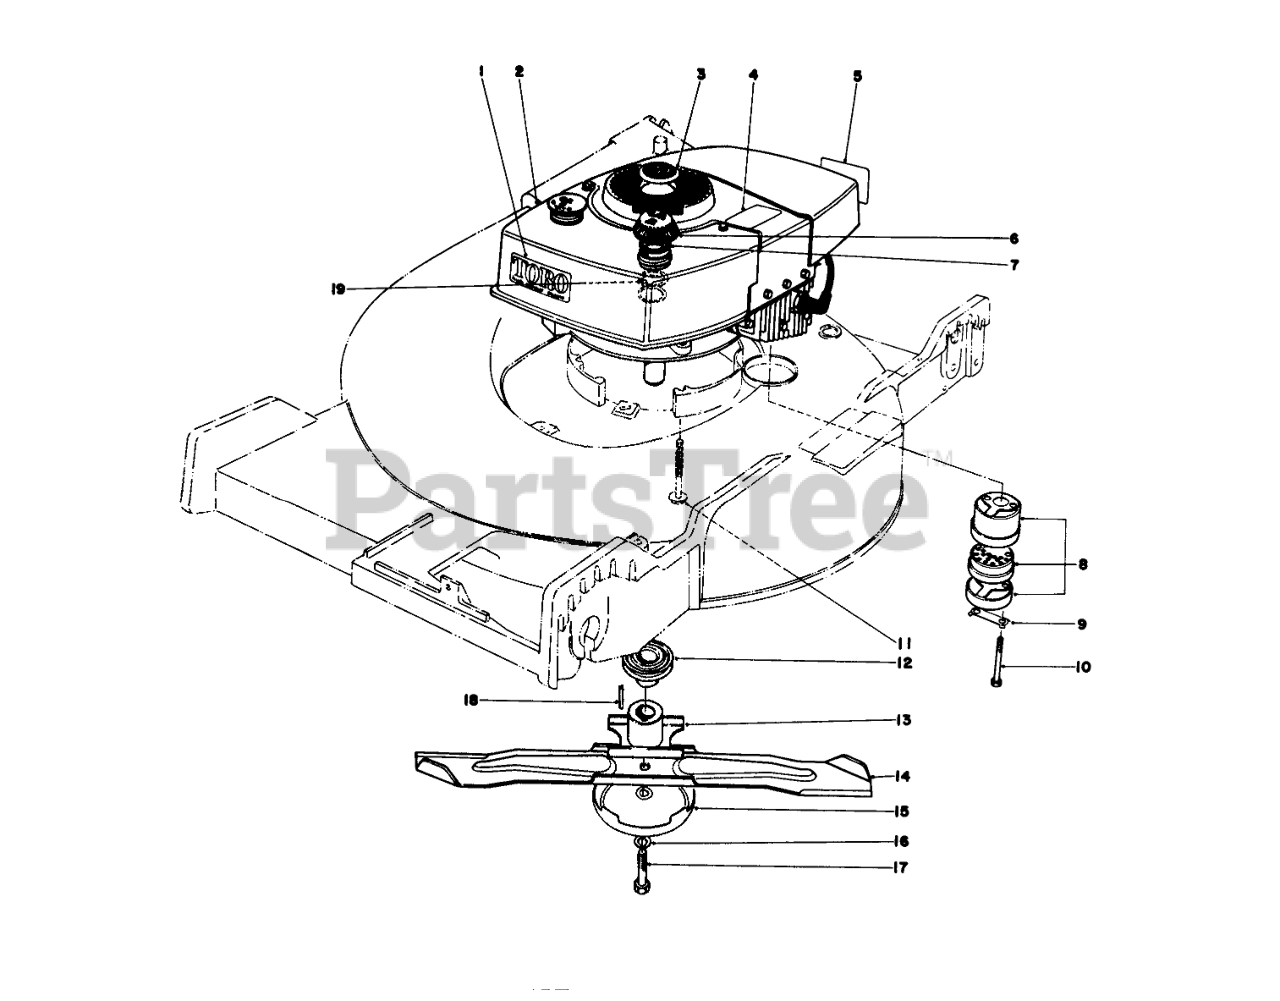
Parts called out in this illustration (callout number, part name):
1	High Torque
2	Engine
3	Plug Button
4	Decal Lockout
5	Decal Maintenance
6	Gas Cap Assembly (Incl. Ref. #7 & 19)
7	GASKET
8	Muffler Assembly (Incl. Ref. #9 & 10)
9	CLIP - LOCKING
10	SCREW-HH
11	3/8-16 X 2-3/4 CAPSCR
12	DRIVER PULLEY
13	BLADE RETAINER WA(BLACK)
14	Blade
15	AntiScalp Cup
16	WASHER-LOCK
17	BLADE SCREW
18	KEY-SQUARE
19	GAS CAP BAFFLE
